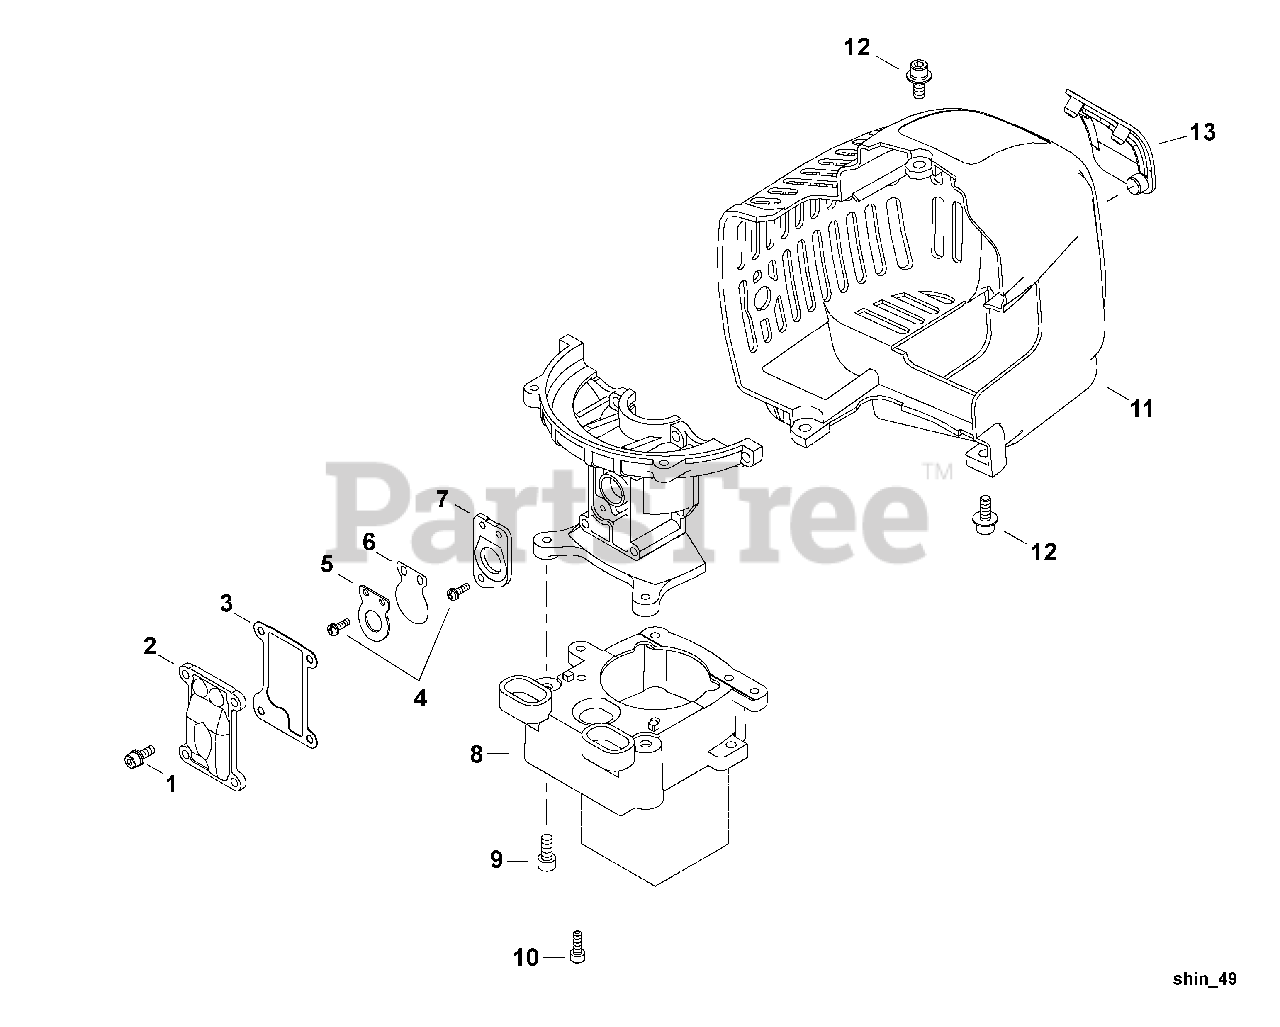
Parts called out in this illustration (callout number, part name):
1	SCREW - 4X12
2	COVER, REED VALVE
3	GASKET, REED VALVE
4	SCREW - 3X10
5	STOP, REED VALVE
6	VALVE, REED
7	PLATE, REED BACKING
8	GEAR CASE ADAPTOR
9	SCREW - 5X12
10	SCREW - 4X12
11	COVER, ENGINE
12	SCREW - 5X14
13	COVER, SPARK PLUG
